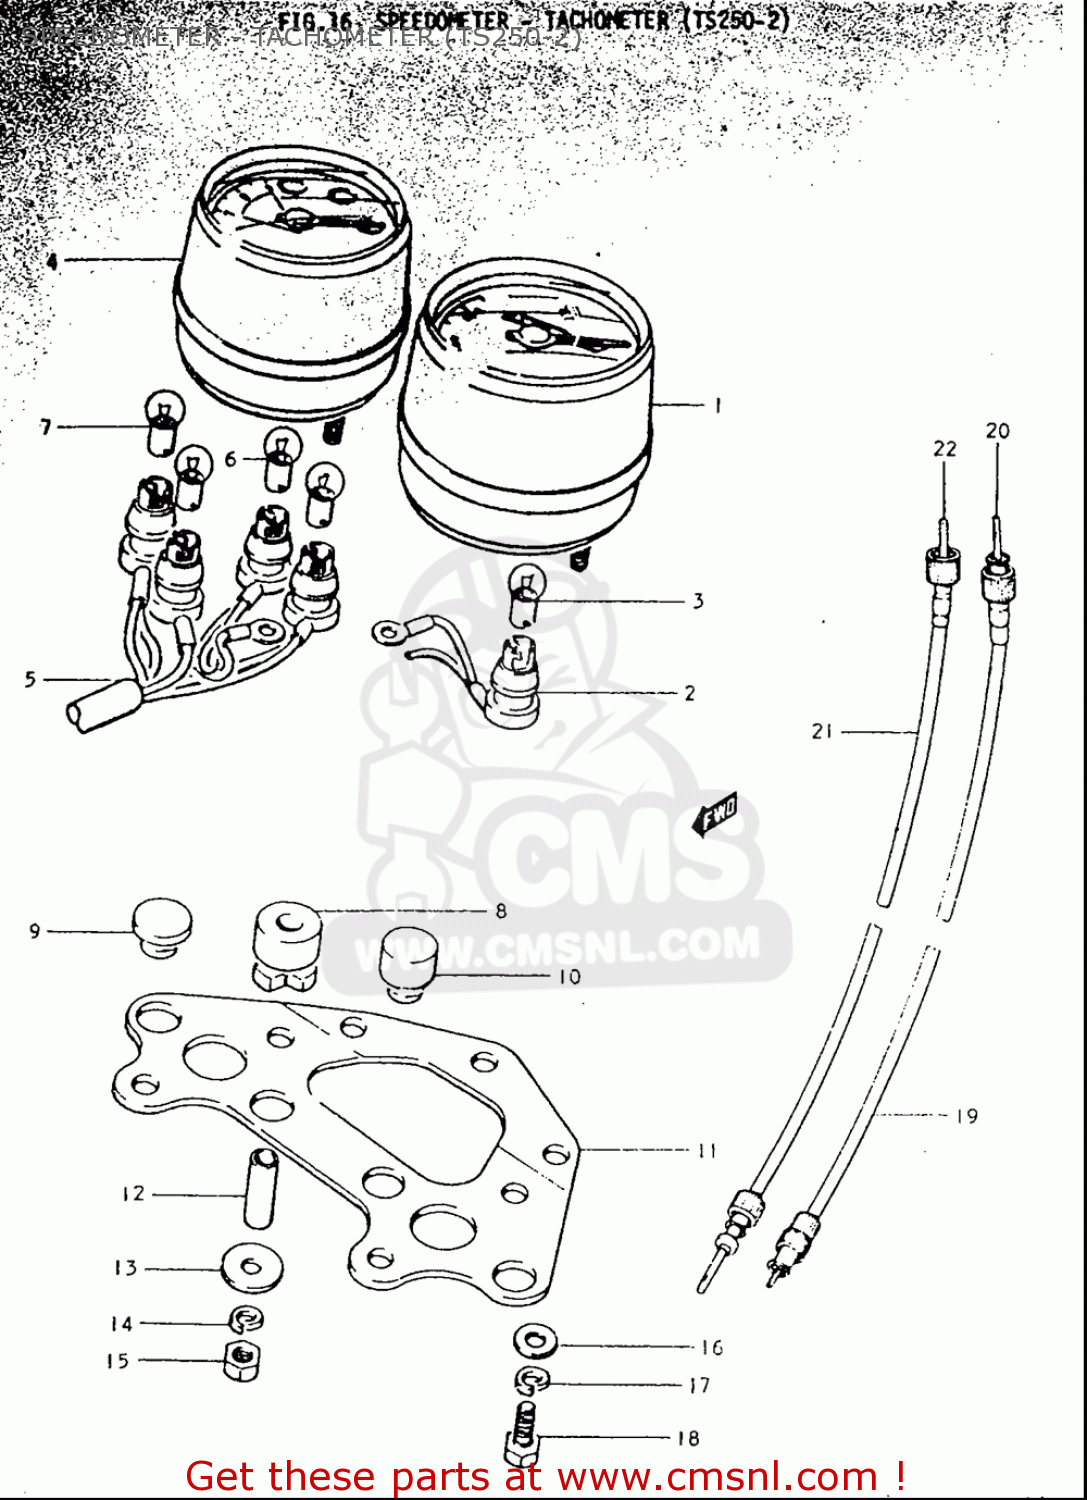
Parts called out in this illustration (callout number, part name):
3	BULB(6V/3W)
6	BULB(6V/3W)
7	BULB(6V1.7W,STANLEY,A61A)
8	CUSHION,METER NO.1
13	WASHER(6.5X18X1.6)
14	WASHER,LOCK
15	NUT
16	WASHER
17	WASHER,LOCK
19	CABLE ASSY,SPEEDOMETER
21	CABLE ASSY,TACHOMETER
